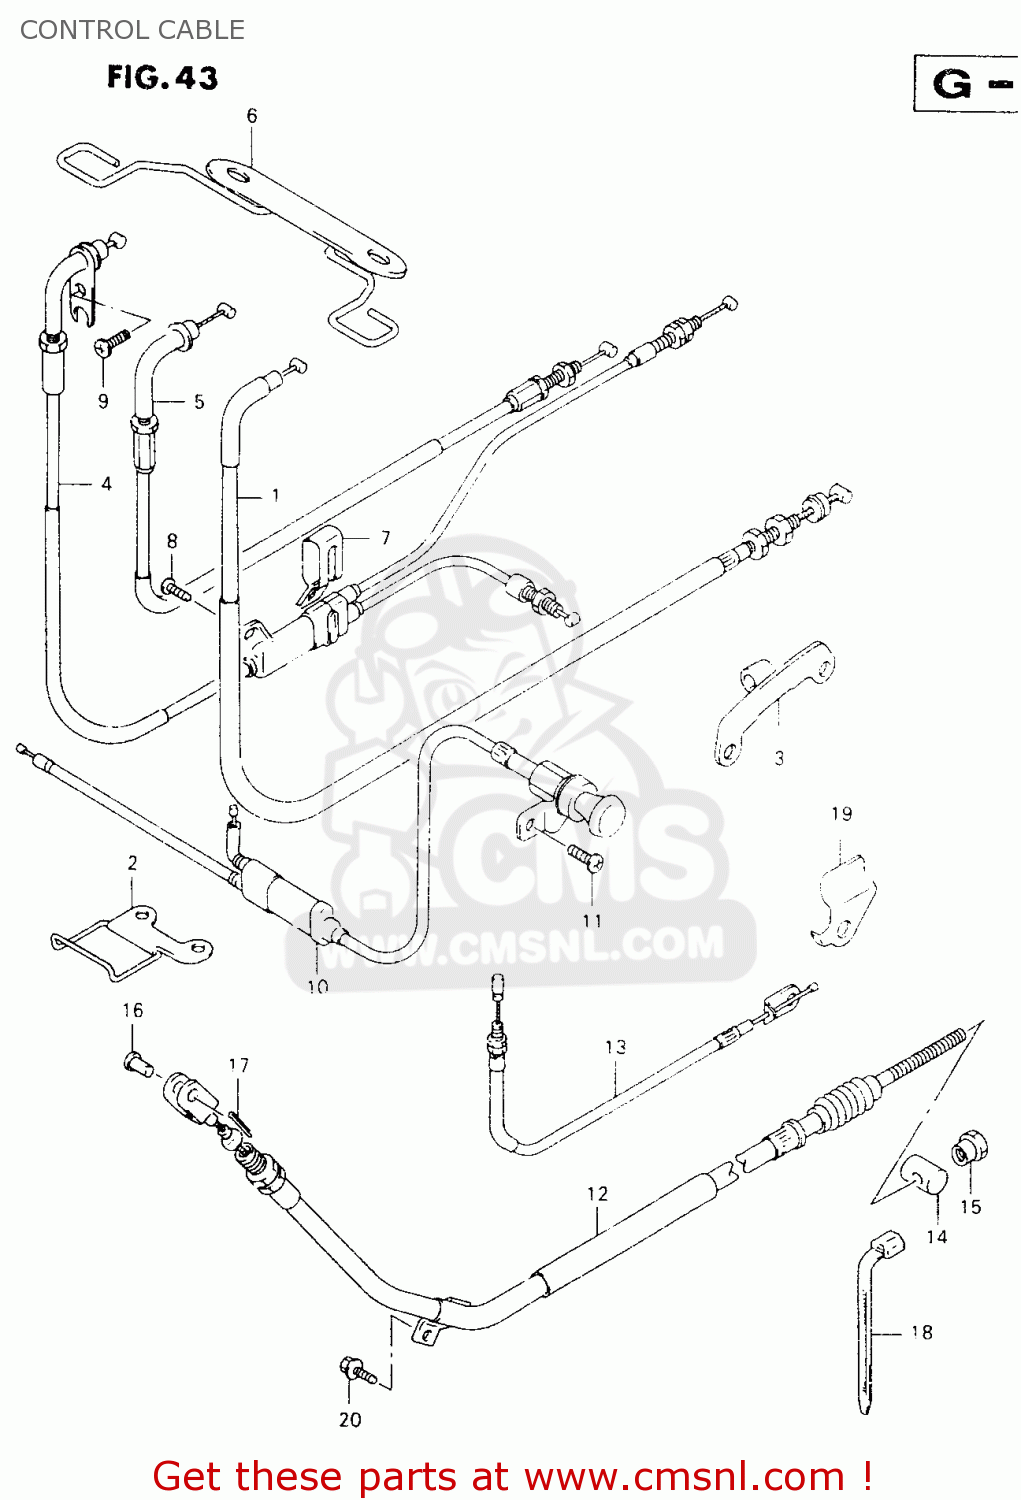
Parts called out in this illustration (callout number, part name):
1	CABLE ASSY,CLUTCH
2	GUIDE,CLUTCH CABLE
3	STOPPER,CLUTCH CABLE
4	CABLE ASSEMBLY,THROTTLE
5	CABLE ASSEMBLY,THROTTLE NO
6	GUIDE,CABLE
7	CLAMP,THROTTLE CABLE CONNECTOR
8	SCREW
9	SCREW
10	CABLE ASSY,STARTER
11	SCREW(6X10)
12	CABLE,RR BRAKE
13	CABLE,STOP LAMP SWITCH
14	PIN(13X18)
15	NUT
16	PIN(L:17.5)
17	PIN
18	CLAMP(L:125)
19	CLAMP,RR BRAKE CABLE
20	BOLT
